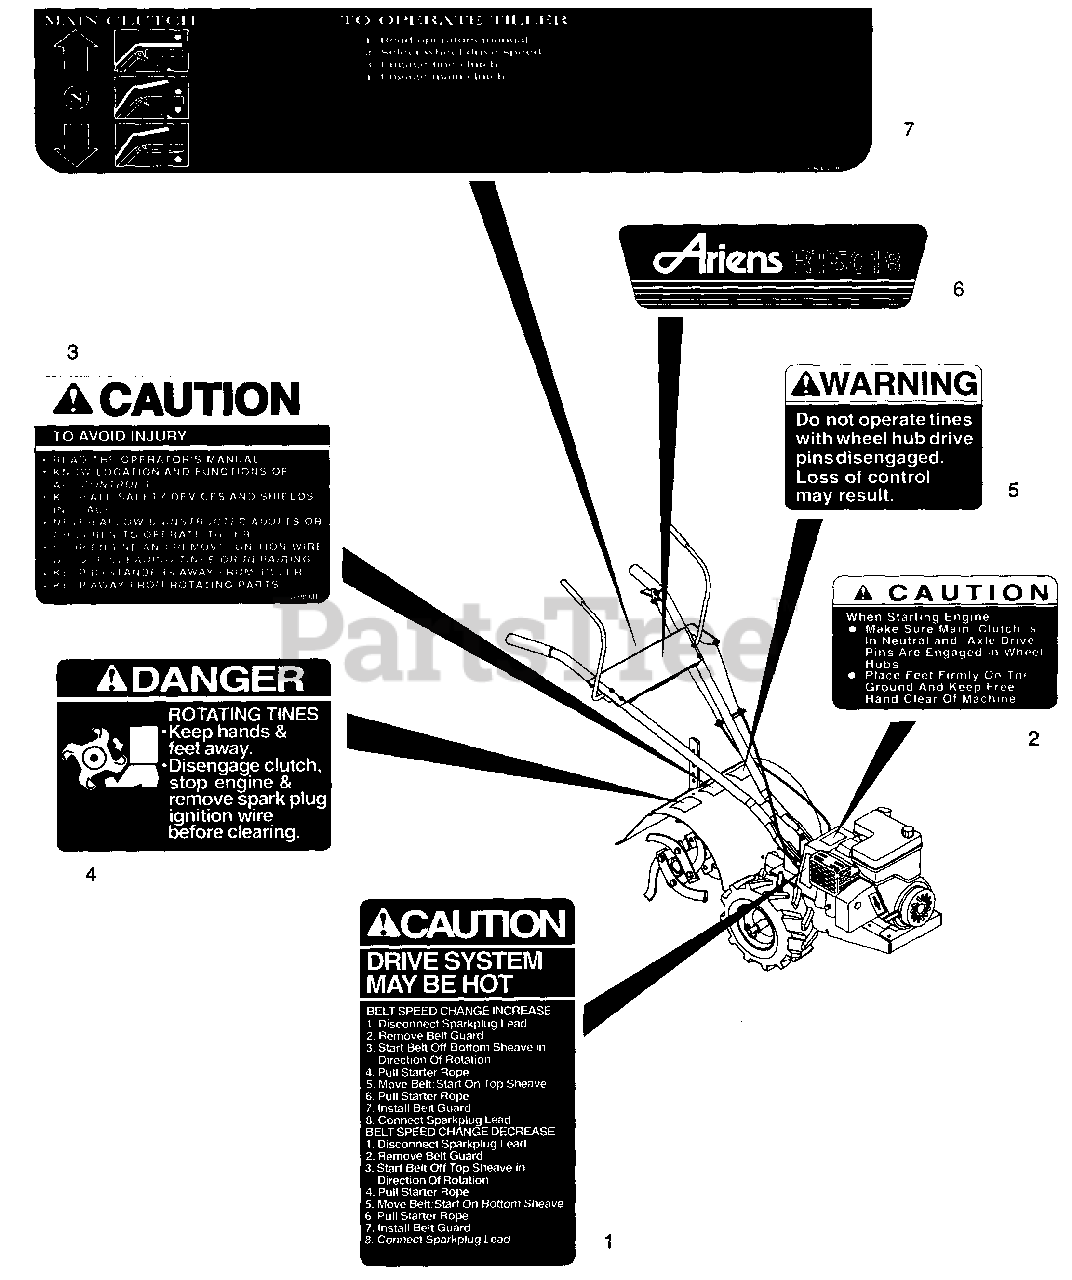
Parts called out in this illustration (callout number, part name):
1	CAUTION DECAL
2	DECAL, CAUTION
3	DECAL-CAUTION TO AVOID INJURY
4	DECAL - DANGER ROTATING TINES
5	DECAL, WARNING
6	DECAL, RT 5018
7	DECAL, DASH CONTROL SER. 18"
